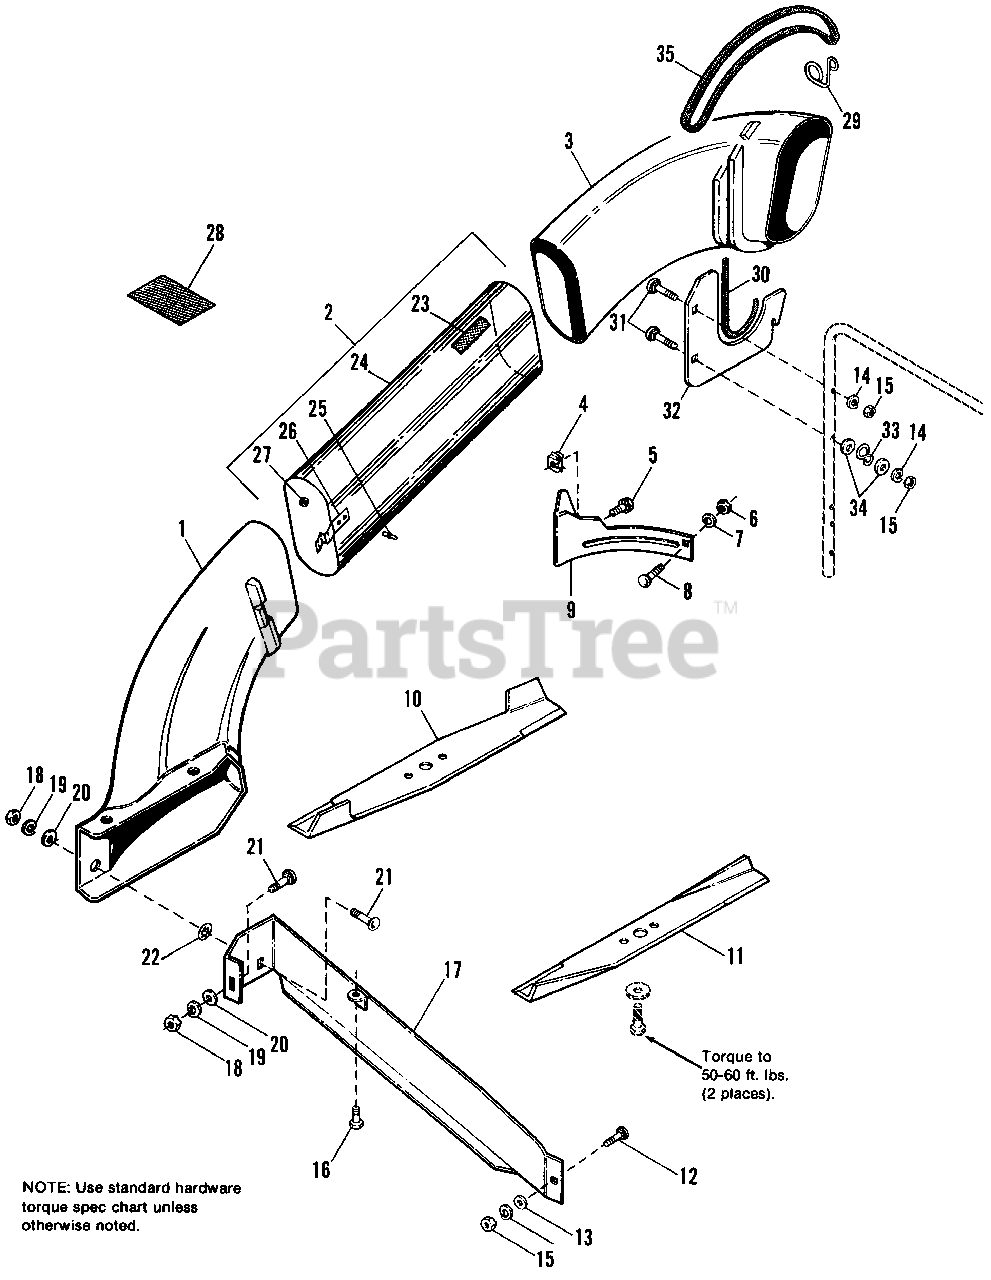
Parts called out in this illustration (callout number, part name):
4	NUT, Retainer, 1/4-20
5	SCREW, Whizlock, 1/4-20 x 1/2
6	NUT, Hex, 1-4-20
7	LOCKWASHER, 1/4
8	CARRIAGE BOLT, 1/4-20 x 5/8
9	BAFFLE, Deflector Side
10	BLADE, R.H.
11	BLADE, L.H.
12	CARRIAGE BOLT, 5/16-18 x 7/8
13	WASHER, 1/4
14	LOCKWASHER, 5/16
15	NUT, Hex, 5/16-18
16	SCREW, Taptite, 5/16-18 x 1/2
17	BAFFLE ASSY., Discharge
18	NUT, Hex, 3/8-16
19	LOCKWASHER, 3/8
20	WASHER, 3/8
21	CARRIAGE BOLT, 3/8-16 x 3/4
22	NUT, Push On
23	DECAL, (Cleaning Instructions)
26	SPRING, Tube, Retaining
27	WASHER, Rivet
28	DECAL, Warning, Cover
29	HOOK, Strap
31	BOLT, Rd. Hd., 5/16-18 x 1-3/4
32	BRACKET, Saddle
34	WASHER, 5/16
35	STRAP, Rubber
